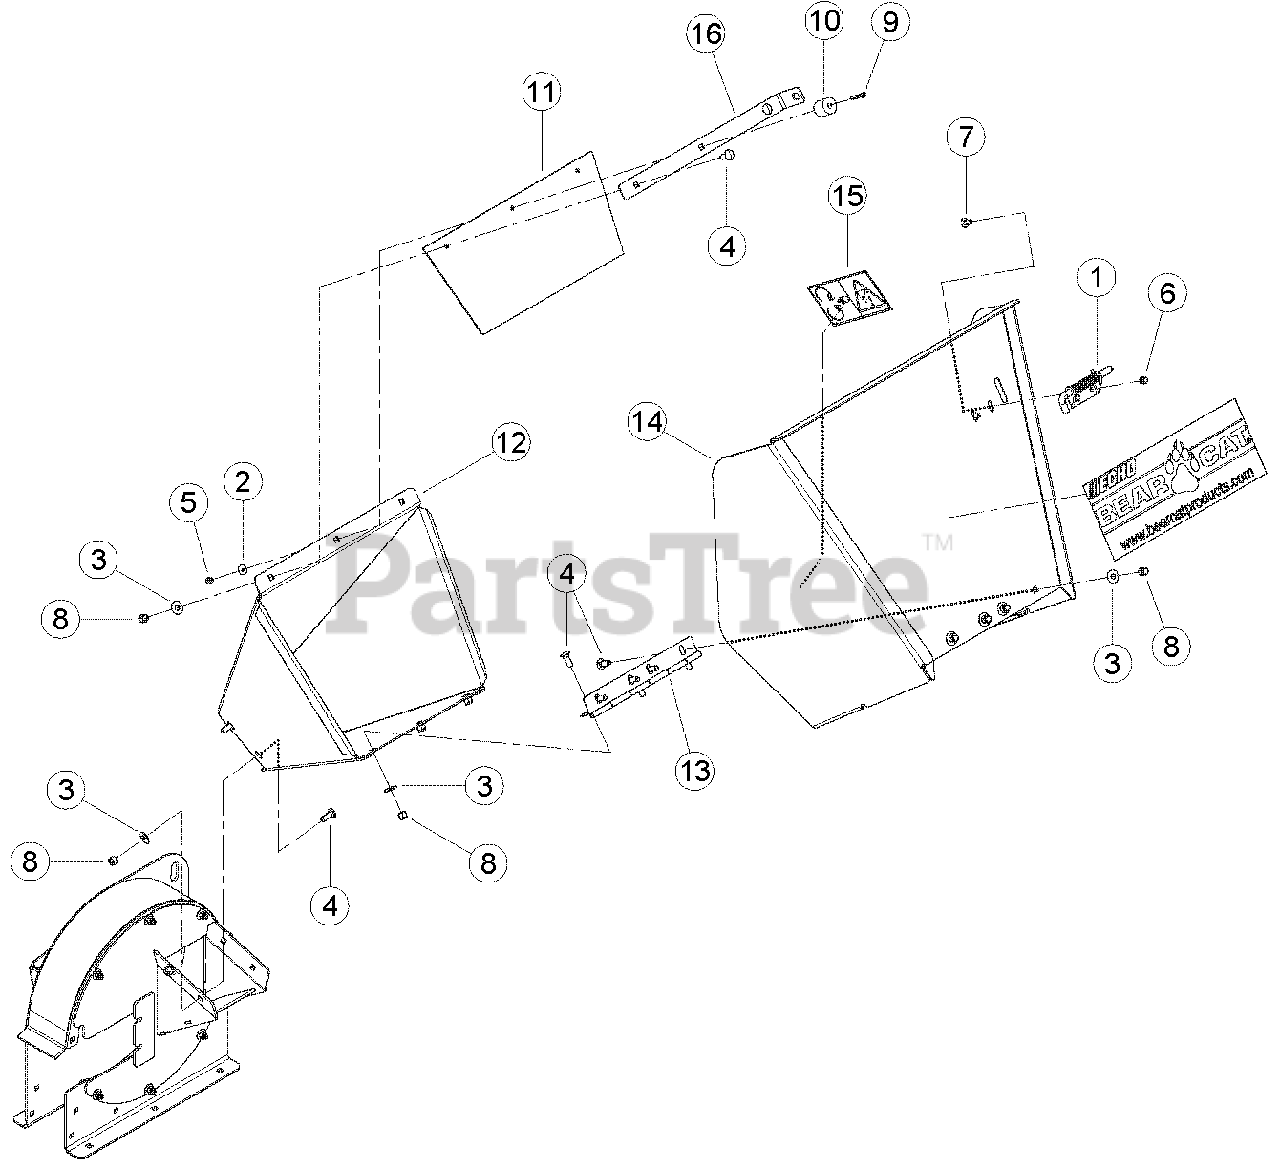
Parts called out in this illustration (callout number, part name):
1	LATCH, RH HINGE
2	WASHER, 1/4 FLAT ZP
3	WASHER, 3/8 FLAT ZP
4	BOLT, 3/8 X 1 CRG GR5 NC ZP
5	NUT, 1/4 NE NYLOCK ZP
6	NUT, 5/16 NE NYLOCK ZP
7	BOLT, 5/16 X 3/4 CRG GR5 NC ZP
8	NUT, 3/8 NE NYLOCK ZP
9	SCREW, 1/4 X 1-1/2 SKT HD CAP
10	BUMPER, RECESSED RUBBER
11	FLAP, CHIPPER CHUTE
12	WELDMENT, HOPPER
13	HINGE, CHUTE EXTENSION
14	ASSEMBLY, 4-1/2" EXTENSION TRAY, SERVICE PART
15	DECAL, BLADE DANGER ISO
16	STRIP, FLAP RETAINER
